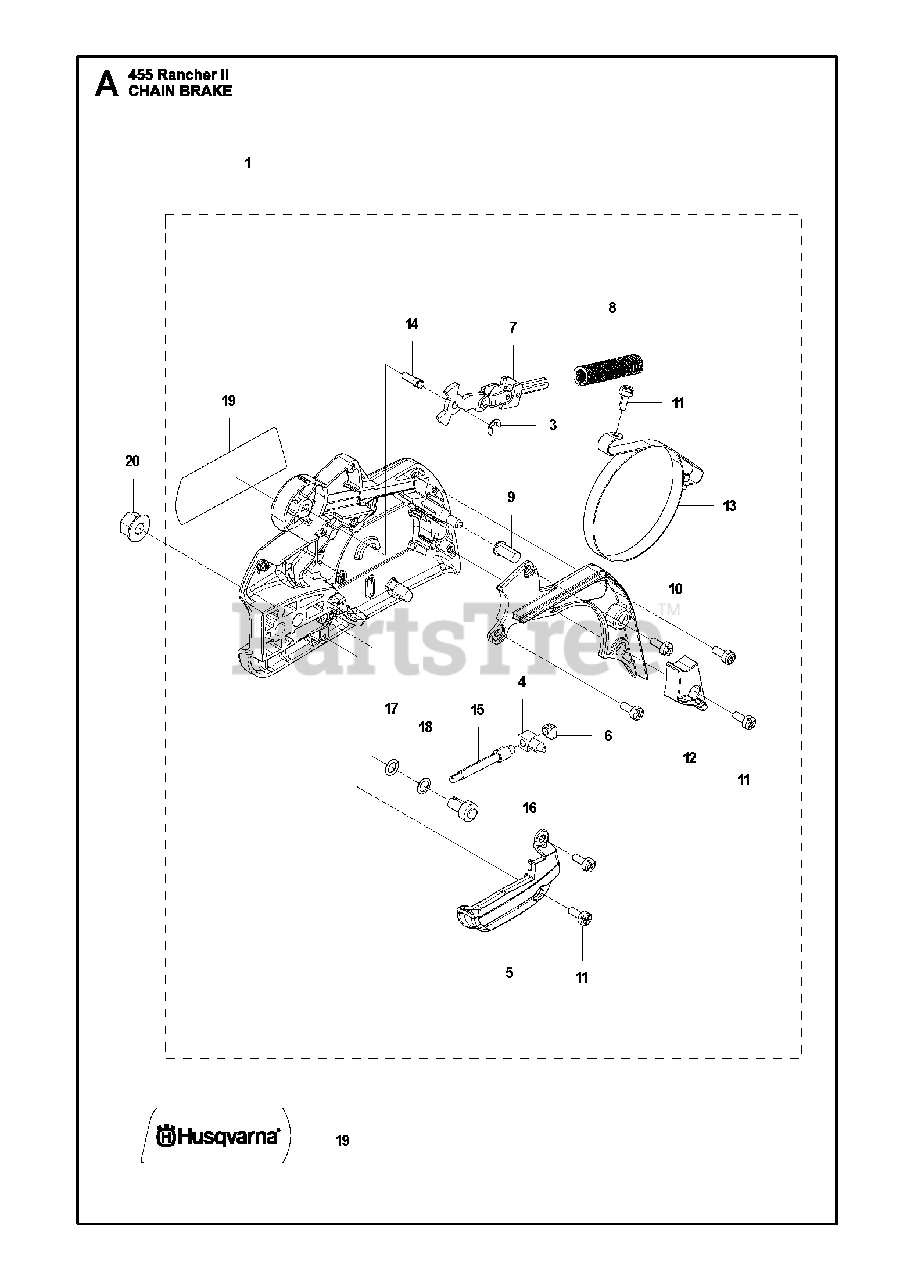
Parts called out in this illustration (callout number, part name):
1	CLUTCH COVER
3	E-RING 4
4	PAWL
5	CHAIN GUIDE
6	SLEEVE
7	JOINT
8	SPRING
9	SLEEVE
10	COVER, CHAIN BRAKE
11	SCREW
12	WEAR GUARD, CHAIN
13	BRAKE BAND
14	PIN
15	SCREW
16	WORM WHEEL
17	O-RING
18	WASHER
19	LABEL 400 SERIES
20	NUT M8 FLANGE
